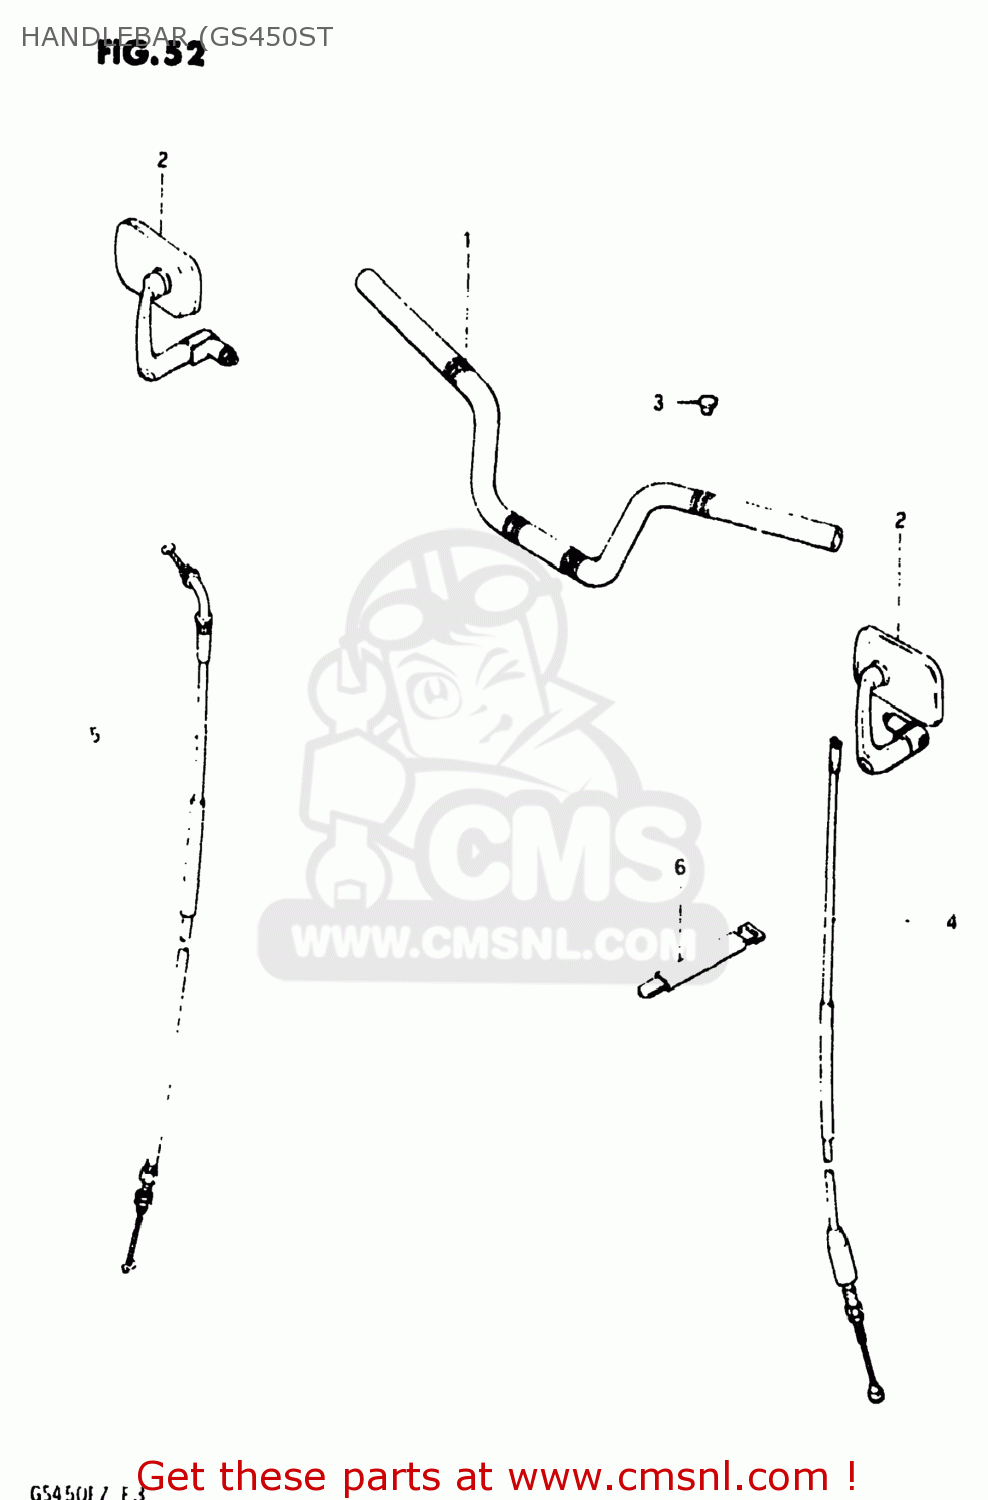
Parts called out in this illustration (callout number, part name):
1	HANDLEBAR
2	MIRROR ASSEMBLY,RIGHT
3	CAP(OD:14)
4	CABLE ASSEMBLY,CLUTCH
5	CABLE ASSEMBLY,THROTTLE
6	CLAMP
